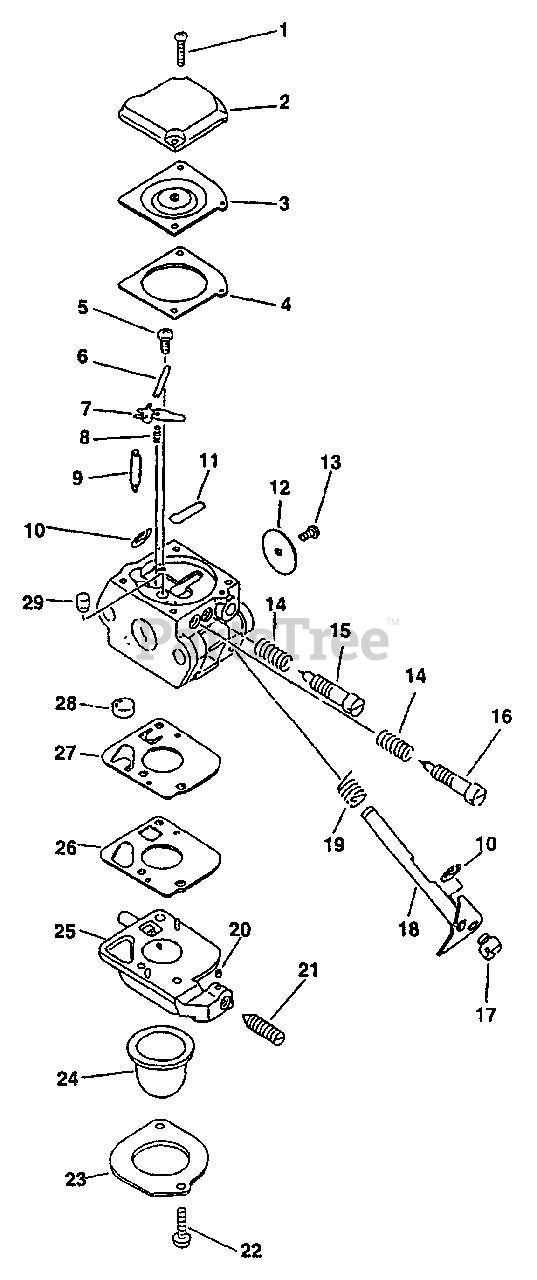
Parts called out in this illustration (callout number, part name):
2	COVER, METERING
3	DIAPHRAGM
4	GASKET, METERING
5	SCREW, METERING LEVER PIN
6	PIN
7	LEVER, METERING
8	SPRING
9	VALVE, NEEDLE
10	RING, RETAINING
11	PLUG, WELCH
12	VALVE, THROTTLE
15	NEEDLE - MIXTURE
16	NEEDLE - HIGH SPEED
18	SHAFT, THROTTLE
19	SPRING, RETURN
20	PIECE, FRICTION
21	SCREW, IDLE ADJUST
22	SCREW, RETAINER
23	RETAINER, PURGE BULB
24	BULB, PURGE
25	BASE, PURGE
26	GASKET, PURGE
27	DIAPHRAGM, PURGE
28	STRAINER
29	NOZZLE, CHECK VALVE
